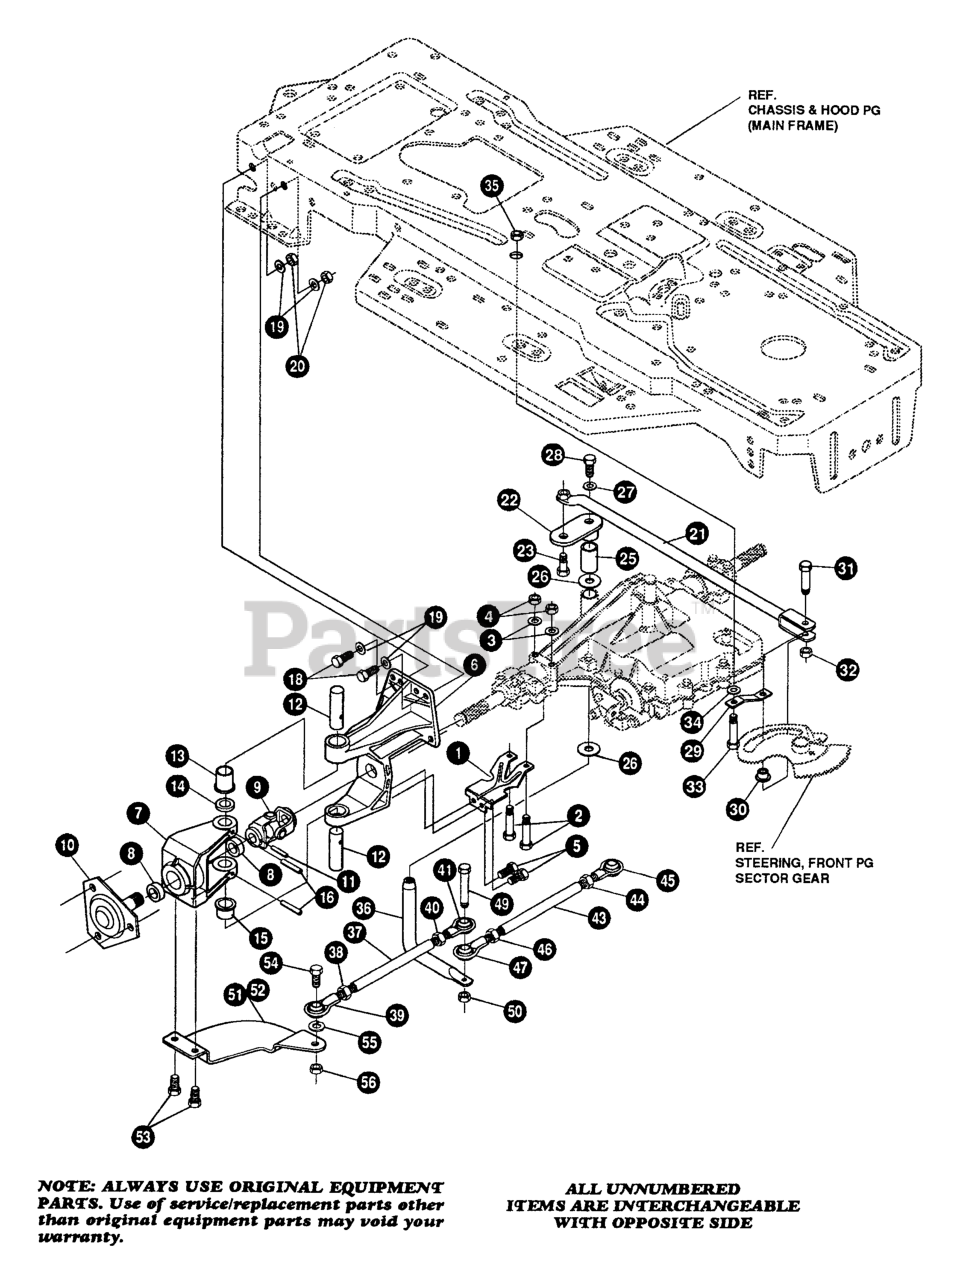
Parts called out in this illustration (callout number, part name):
1	BRACKET, X-AXLE MTG
2	SCREW, 5/16-18 x 2.50
3	WASHER, FLAT .344. x .69 x .065
4	NUT, 5/16-18
5	SCREW, 5/16-18 x 0.75
6	BRACKET, STEERING PIVOT
7	BRACKET, STEERING PIVOT
8	BEARING, BALL
9	U-JOINT ASSEMBLY
10	HUB ASSEMBLY
11	PIN, GROOVED
12	PIN, STEERING HINGE
13	BRACKET ASSEMBLY
14	WASHER, FLAT .765 x 1.25 x .042
15	BRACKET ASSEMBLY
16	PIN, SPRING
18	SCREW, 5/16-18 x 1.00
19	WASHER, FLAT .344 x .69 x .065
20	NUT, 5/16-18
21	ROD ASSEMBLY, DRAGLINK
22	PIVOT, STEERING
23	BOLT, .562 x .340
25	SPACER, STEERING SHAFT
26	WASHER, FLAT .765 x 1.19 x .048
27	WASHER, FLAT .333 x .87 x .119
28	SCREW, 5/16-24 x 1.00
29	FOLLOWER, ROLLER
30	CAM YOKE ROLLER
31	BOLT, .625 X 1.175
32	NUT, 1/2-20
33	BOLT, .265 x .980
34	WASHER, FLAT .391 x 1.00 x .209
35	NUT, 3/8-24
36	SHAFT, STEERING PIVOT
37	ROD, TIE RH
38	NUT, 3/8-24
39	BALL JOINT, LH
40	NUT, 3/8-24
41	BALL JOINT, RH
43	ROD, TIE, LH
44	NUT, 3/8-24 LH
45	BALL JOINT, LH
46	NUT, 3/8-24
47	BALL JOINT, RH
49	SCREW, 3/8-24 x 1.75
50	NUT, 3/8-24
51	REAR WHEEL STEER, RH
52	ARM, REAR WHEEL STEER, LH
53	SCREW, 3/8-16 x .75
54	SCREW, 3/8-24 x 1.25
55	WASHER, .393 x .68 x .10
56	NUT, 3/8-24
